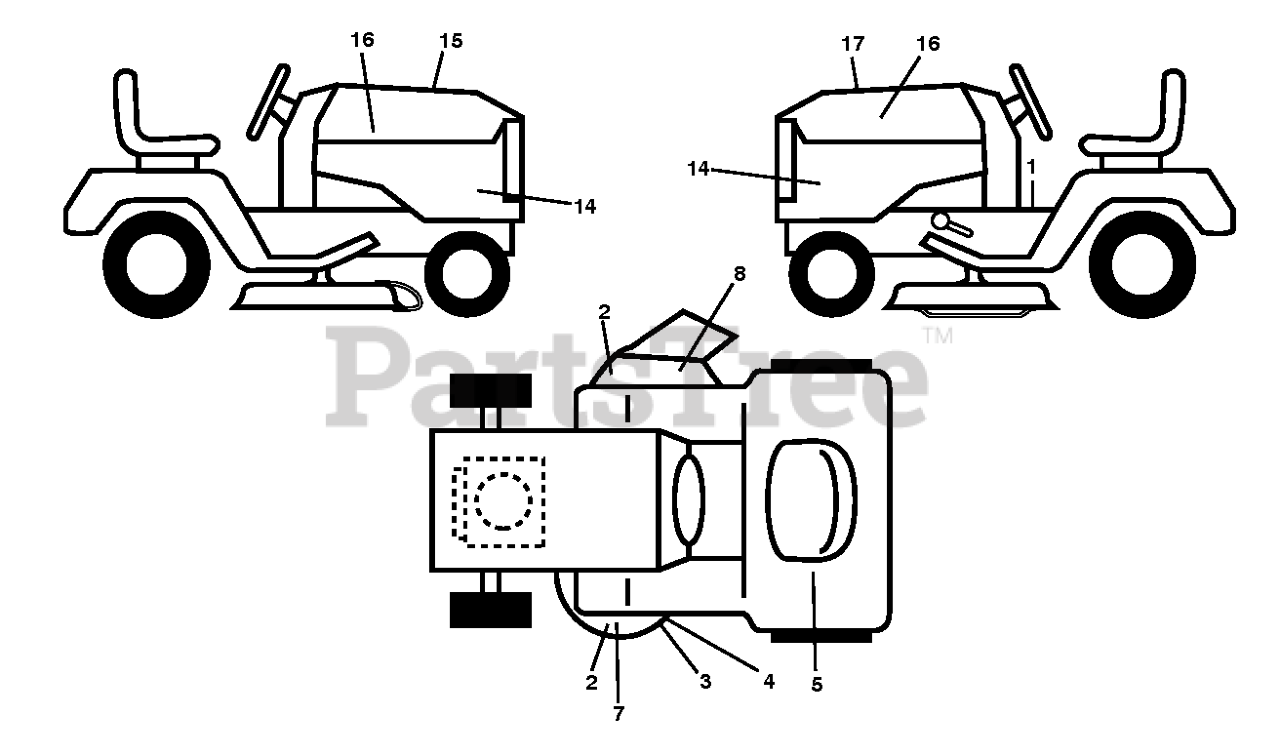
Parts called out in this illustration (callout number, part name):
1	DECAL.FENDER.WARNING.ENGLISH
2	DECAL.DECK.CLEARCUT.NOSTEP
3	DECAL.MOWER.SCH.48/54.PREM
4	DECAL DECK DECAL DECAL.DECK.WA
5	DECAL.RESERVEFUELSELCTR.ENG
7	DECAL DECK DECAL DECAL.48DECK.
8	DECAL.TRACT/ZTR.DECKWARN.HUSQ
14	DECAL TRACTOR SIDE PANEL DECAL
15	DECAL.WARNING.CUST.RESP.E85.
16	DECAL.BADGE.170MM.TEXTLOGO.
17	DECAL.RPL.KW.FR.TGB.48F.K66AL
